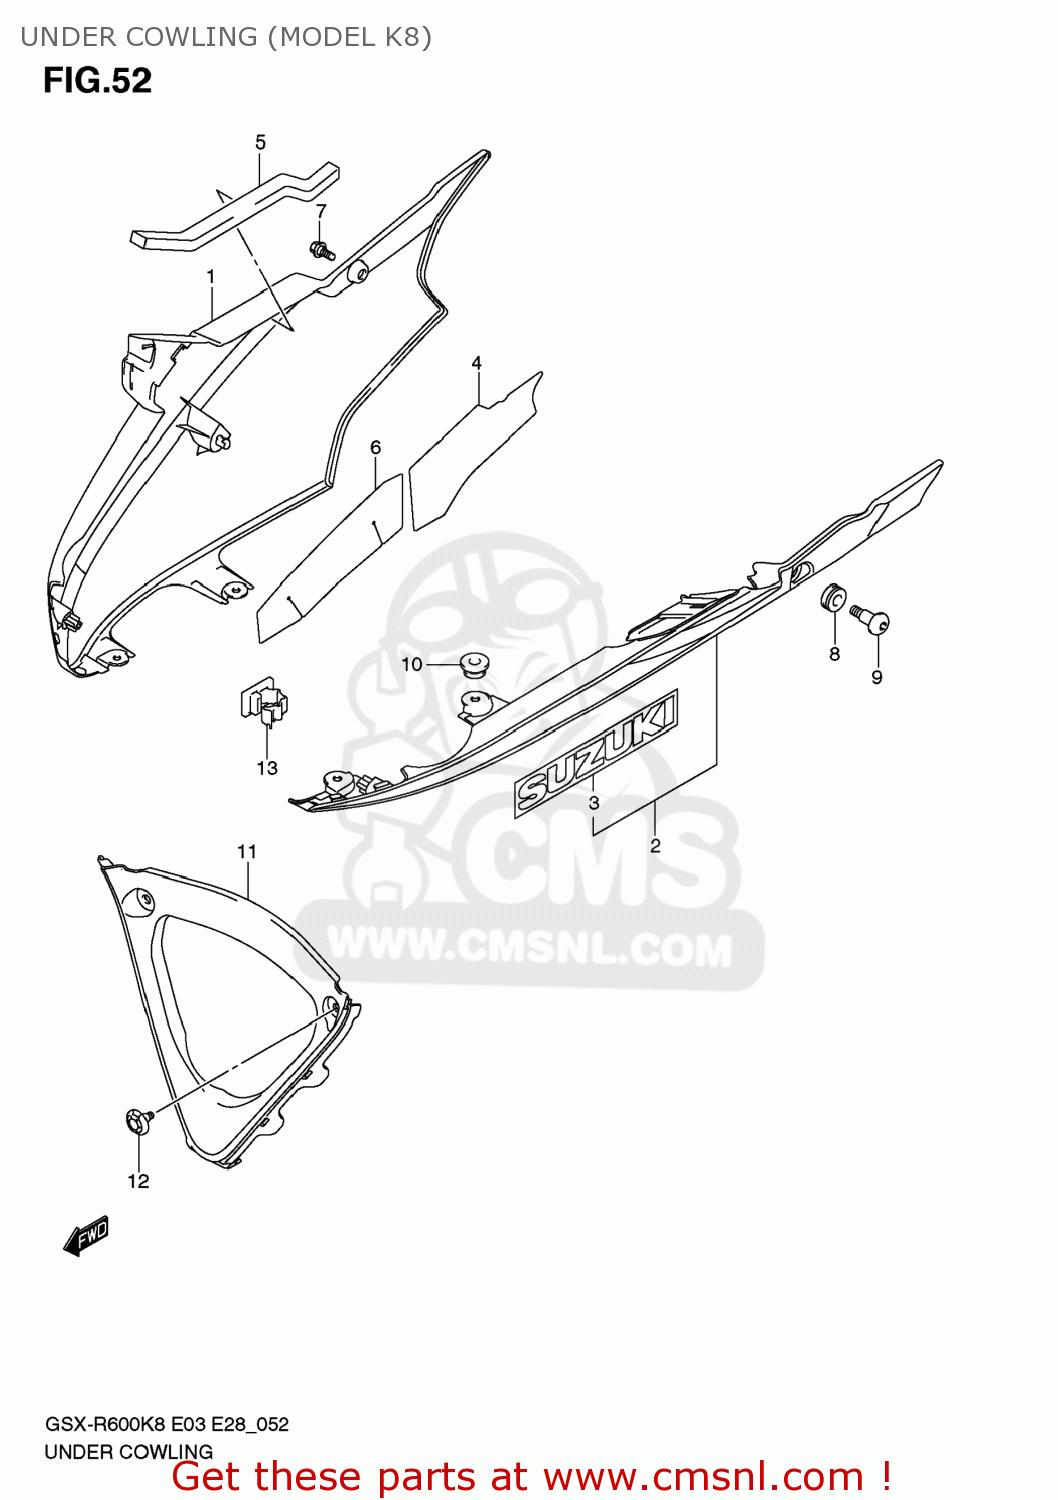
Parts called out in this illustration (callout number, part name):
1	COWLING,UNDER,R(BLACK)
2	COWLING,UNDER,L(BLACK)
3	EMBLEM,SUZUKI
4	SHIELD,UNDER COWL HEAT,R
5	CUSHION,UNDER COWLING
6	SHIELD,UNDER COWL HEAT,R
7	SCREW(5X13)
8	CUSHION
9	SCREW(6X20)
10	CUSHION
11	COWLING,UNDER CTR
12	CLIP
13	CLAMP
